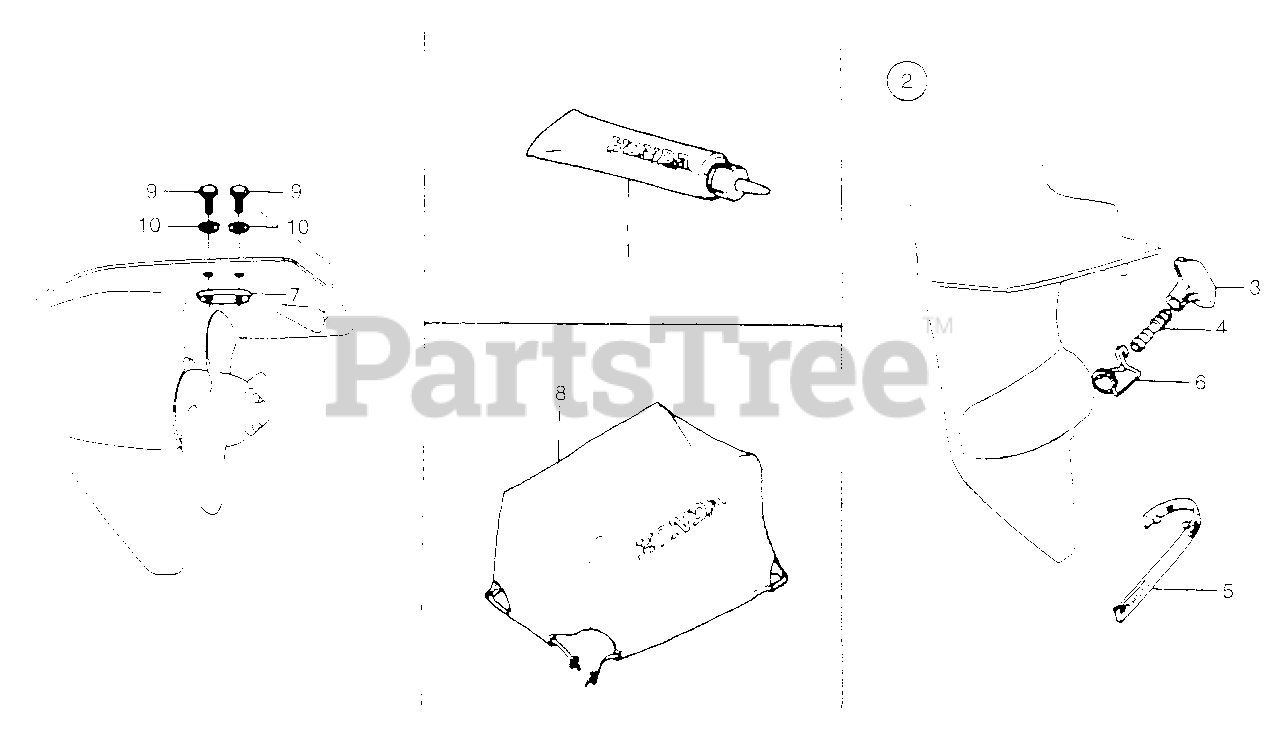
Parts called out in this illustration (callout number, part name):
1	TUBE, GEAR OIL
1	TUBE, GEAR OIL (NOT AVAILABLE)
2	MOUTH KIT, WATER
2	MOUTH SET, WATER
3	MOUTH, WATER
4	JOINT, HOSE (NOT AVAILABLE)
5	PLUG, WATER (NOT AVAILABLE)
6	CLIP, WATER MOUTH
7	METAL, ANODE
8	COVER, BODY (NOT AVAILABLE)
8	COVER, BODY
9	BOLT, HEX. (6X16)
10	WASHER, PLAIN (6MM)
